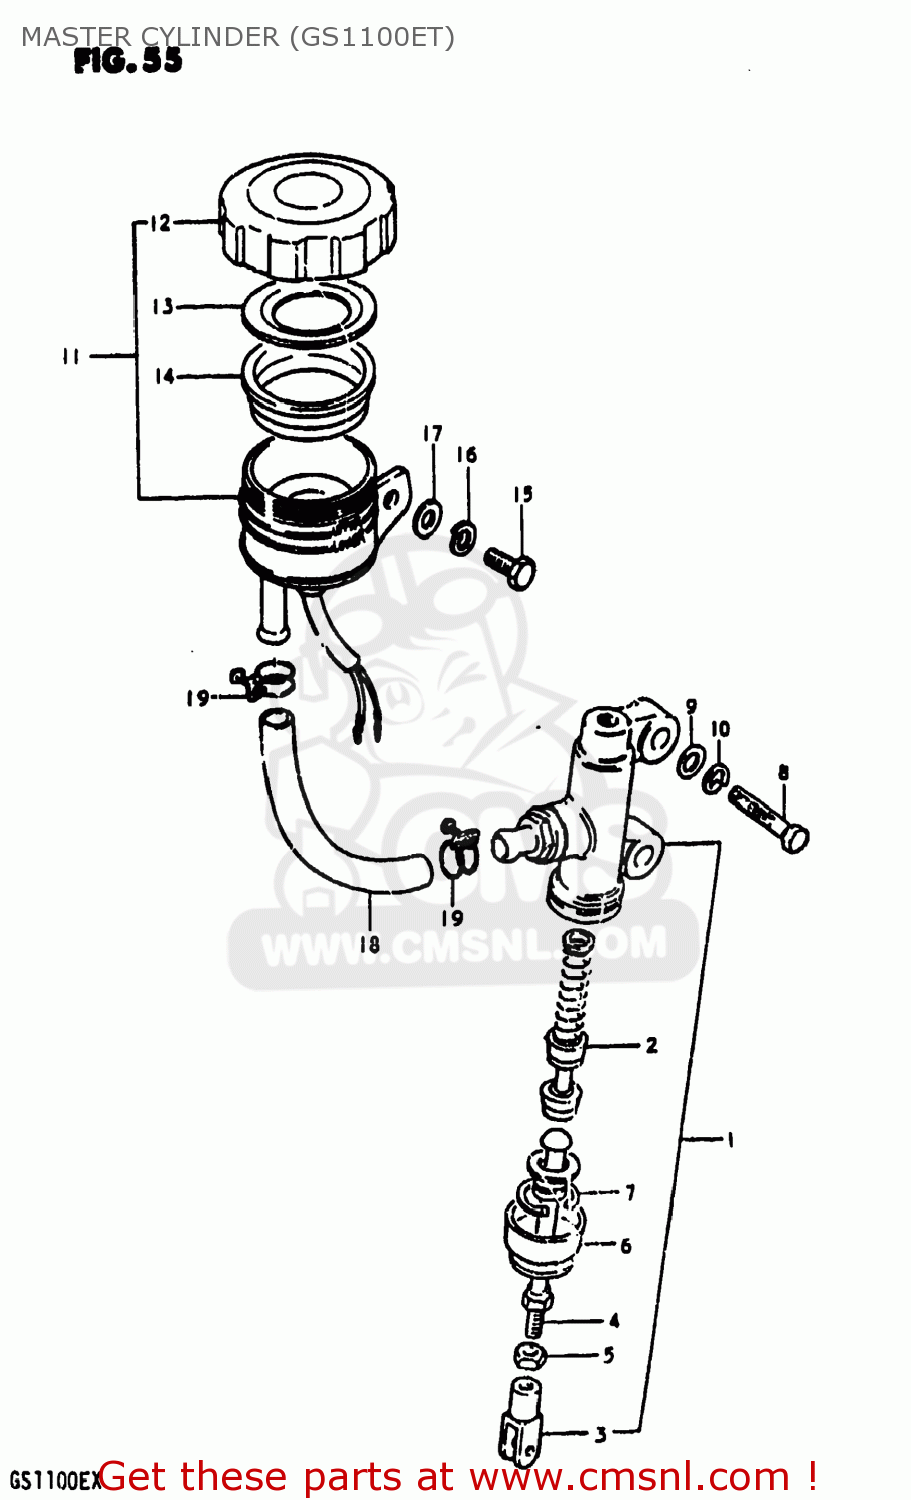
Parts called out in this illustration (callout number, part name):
1	CYLINDER ASSEMBLY,REAR MASTER
2	PISTON/CUP SET
3	YOKE
4	ROD,PUSH
5	NUT
6	BOOT
7	CIRCLIP
8	BOLT (8X30)
9	WASHER
10	LOCK WASHER
12	CAP
13	PLATE,DIAPHRAGM
14	DIAPHRAGM
15	BOLT, UPPER
16	LOCK WASHER
17	WASHER
18	HOSE,RESERVOIR TANK
19	CLAMP
